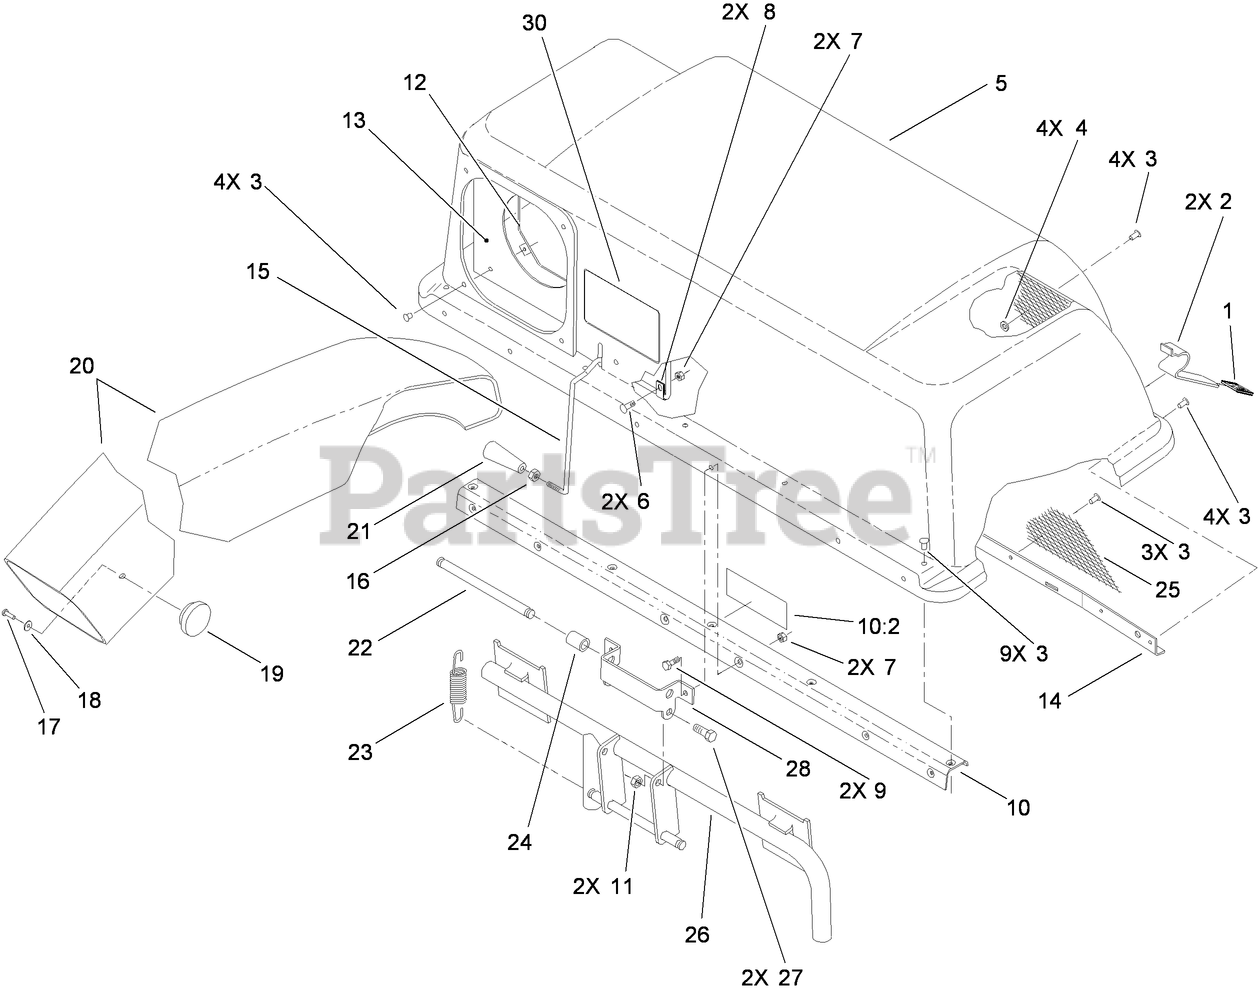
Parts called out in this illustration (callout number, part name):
2	LATCH-BAGGER, TOP
3	RIVET-BLIND
4	WASHER-FLAT
5	TOP-BAGGER
6	SCREW-HH
7	NUT-LOCK, NI
8	CLAMP
9	SCREW-HH
10	BAG STIFFENER ASM
10:2	DECAL-CAUTION
11	NUT-LOCK, NI
12	CLAMP-SEAL
13	SEAL-CHUTE
14	SUPPORT-SCREEN
15	FEELER-FILL, BAG
16	NUT-JAM
17	SCREW-PPHTF
18	WASHER-PLAIN
20	CHUTE-DISCHARGE
21	HANDLE-TAPERED
22	PIN-SPRING
23	SPRING-EXTENSION
24	SPACER
25	SCREEN-BAGGER
26	FRAME ASM
27	SCREW-HH
28	HINGE-BAG, TOP
30	DECAL
